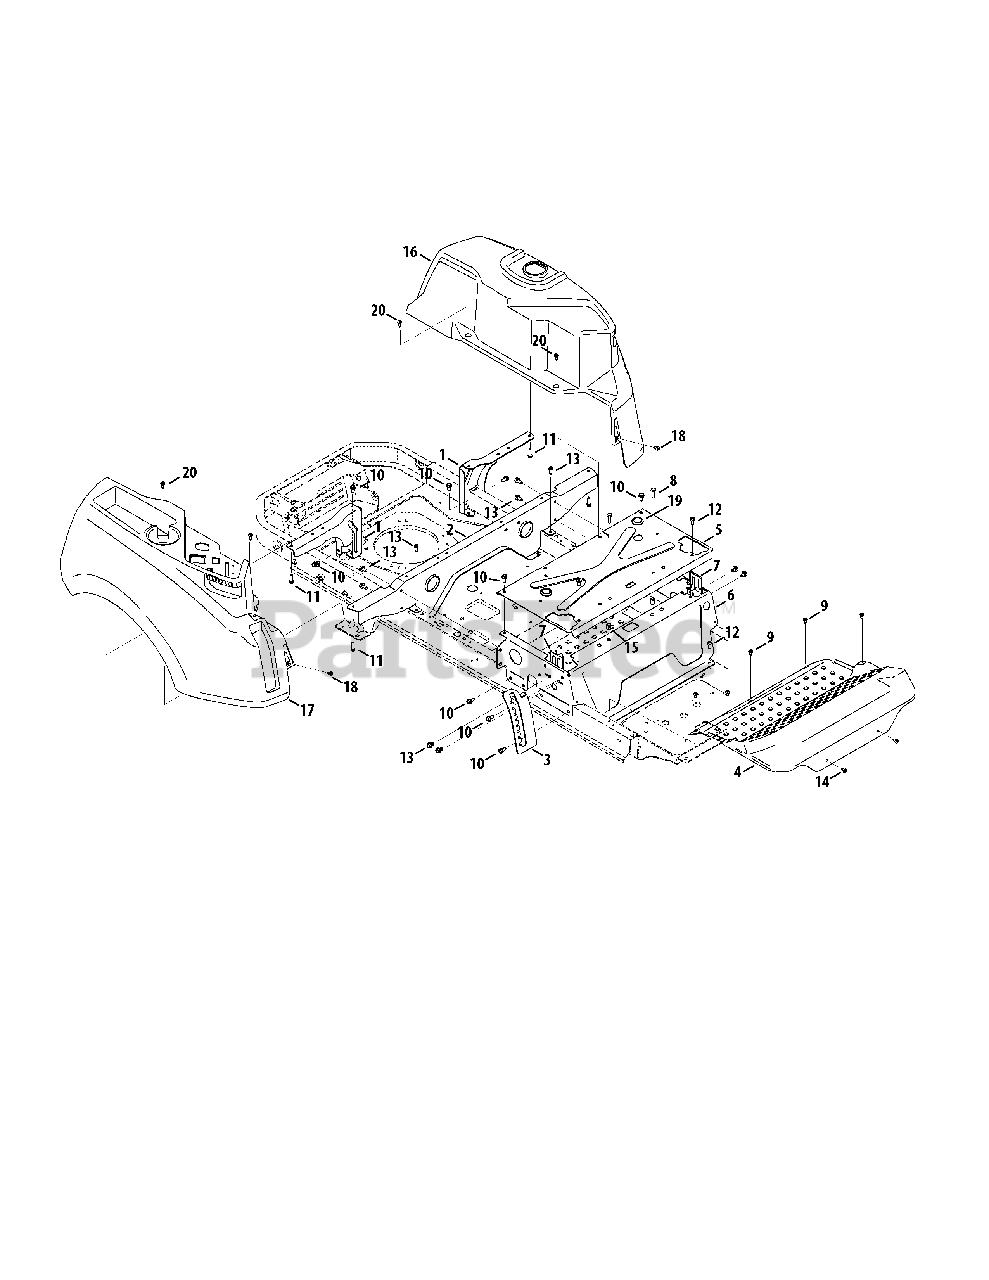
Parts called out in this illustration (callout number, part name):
1	Rear Tank Bracket
2	Rear Seatbox Brace
3	Height Index Bracket
4	Floor Board
5	Seatbox Plate
6	Seat Frame
7	Lapbar Brace Bracket
8	Hex Cap Screw, 5/16-18 x 1.00
9	Screw, 1/4-20 x .5
10	Hex Washer Screw, 5/16-18 x .750
11	Hex Washer Screw, 5/16-14 x 1.00
12	Self Tapping Screw, 5/16-18 x .750
13	Hex Washer Screw, 5/16-18 x .50
14	Screw, 5/16-18, .750
15	Nut, 5/16-18
16	LH Console
17	RH Console
18	Shoulder Screw, 1/4-20
19	Button Plug
20	Shoulder Screw, .368 x .115, M6-1
